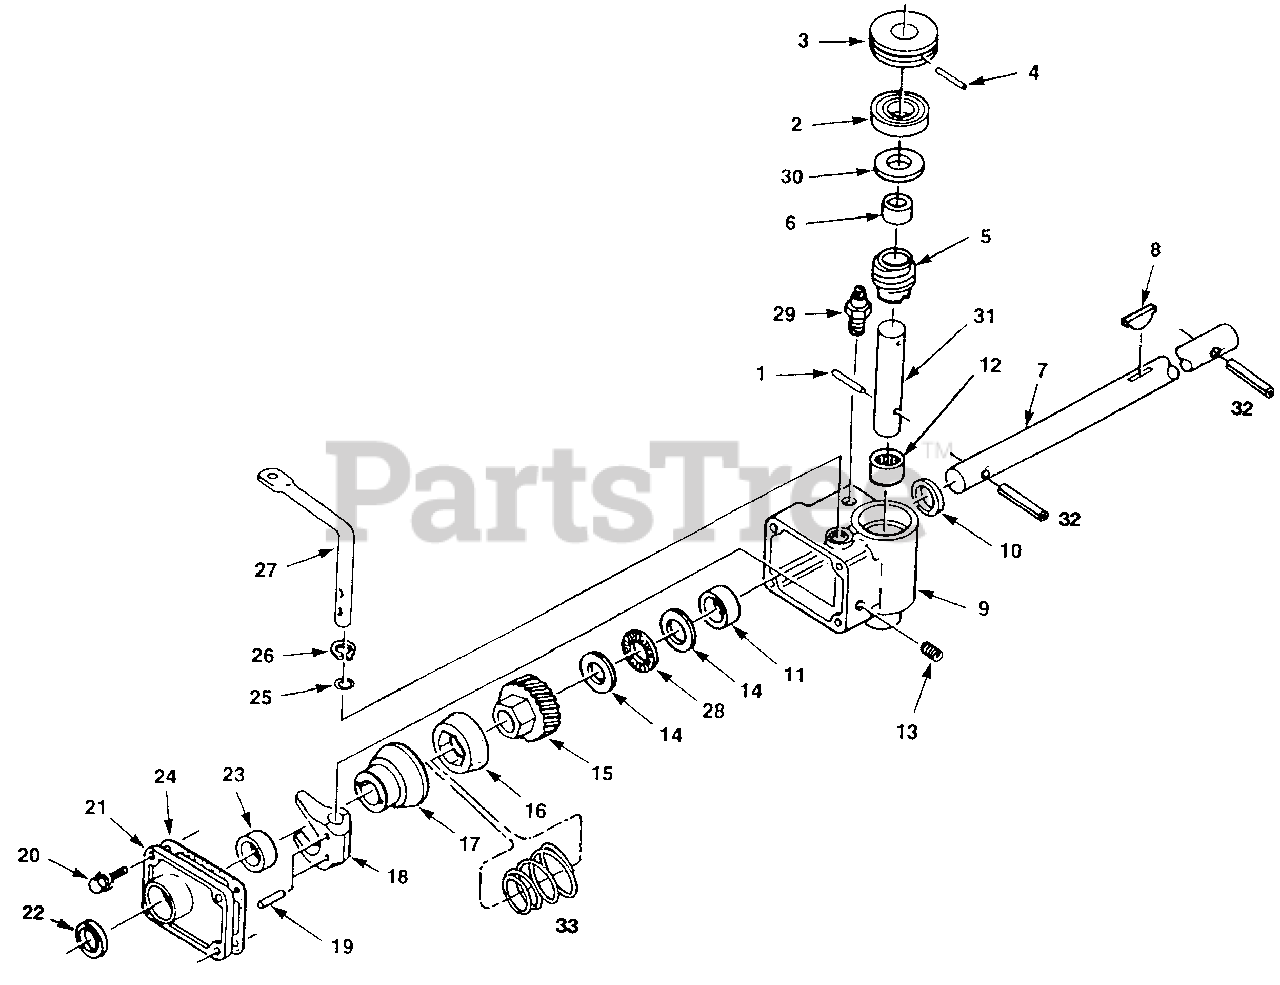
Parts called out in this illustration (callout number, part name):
1	PIN - Roll 3/16 x 7/8
2	BEARING - Ball
3	PULLEY - Gear box
4	PIN-ROLL 3/32 x 1 1/4"
5	WORM & SPACER
6	SPACER - Worm
7	SHAFT - Drive
9	HOUSING - Gearbox
11	BUSHING - Sleeve
12	BEARING - Needle
13	PLUG - Pipe
14	RACE - Thrust
15	GEAR - Helical
16	CONE - Friction
17	DRUM - Clutch
18	FORK - Shift
19	PIN - Groove
20	SCREW - (1/4 - 20 x 7/8")
21	COVER - Gear Box
23	BUSHING - Sleeve
24	GASKET - Gearbox
26	TRU-ARC RING
27	LEVER - Shift
28	BEARING - Needle
31	WORM - Shaft
32	PIN - Roll 1/8" x 7/8"
33	SPRING - Clutch
